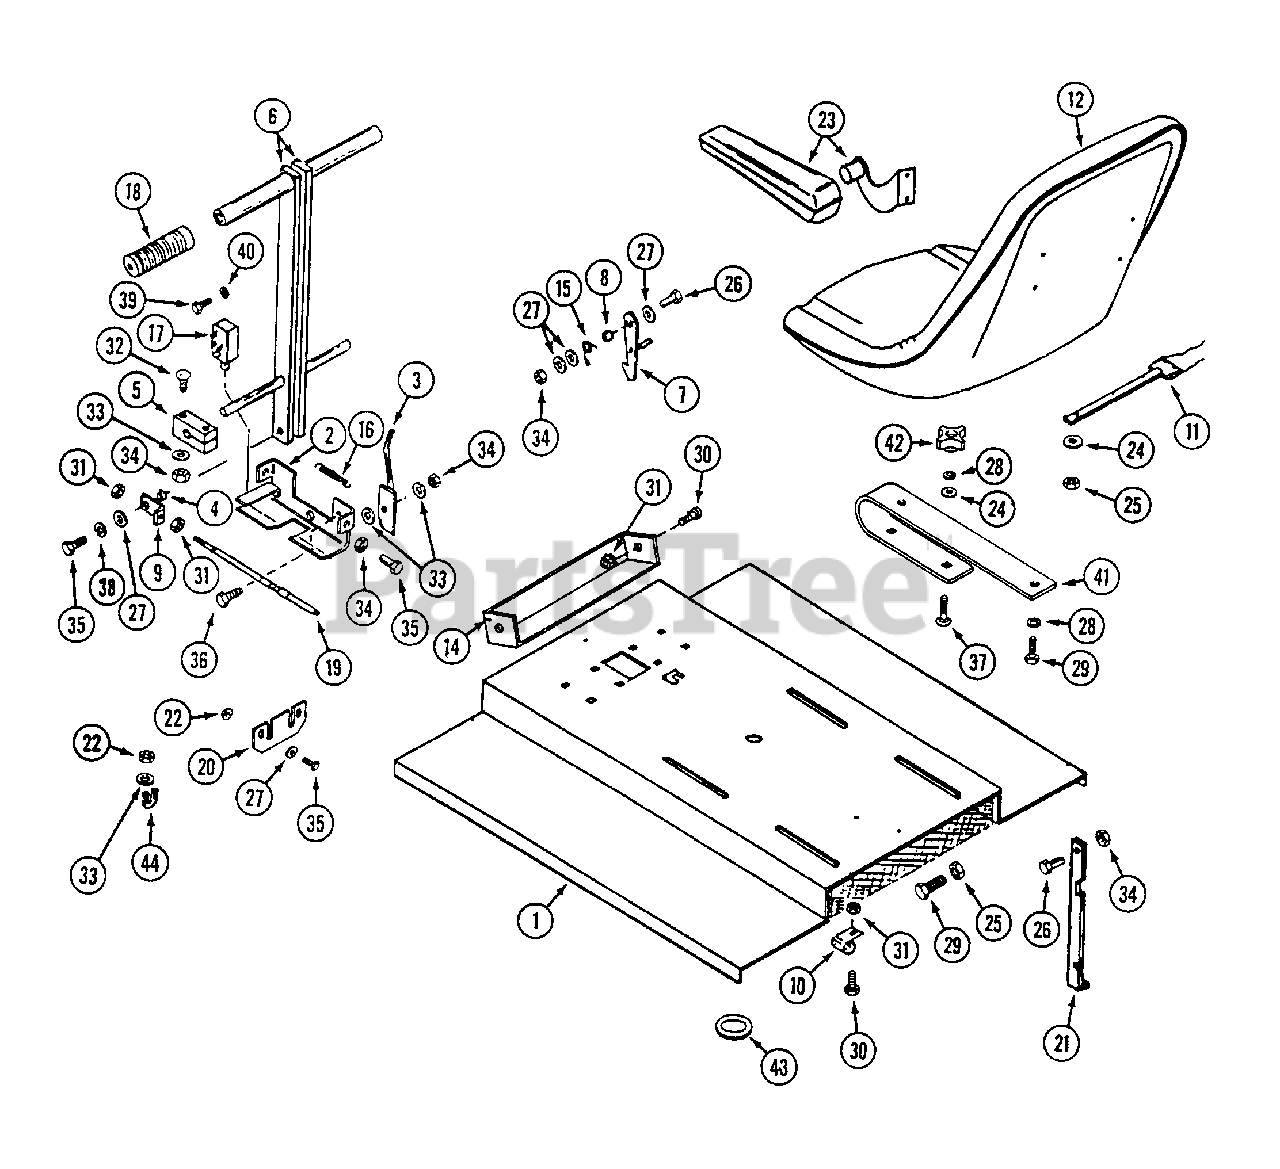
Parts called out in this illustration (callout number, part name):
1	LID - seat
2	BRACKET - lever lock
3	LATCH - lever lock
5	BEARING - block
6	LEVER - steering
7	LATCH - seat lid
8	SPACER - latch
9	BRACKET - steering cable end
10	RETAINER - harness, seat lid
11	SWITCH - seat
14	PLATE - filler
15	SPRING - latch, seat lid
16	SPRING - bracket, lever lock
17	SWITCH - safety
18	GRIP - handle
19	CABLE - steering
20	CLAMP - steering cable
21	PROP - seat lid
22	NOT - 1/4" - 20 flange lock
23	KIT - arm rest
24	WASHER - 5/16"
25	NUT - 5/16"
26	BOLT - 1/4" - 20 x 1-1/4"
27	WASHER - 1/4"
28	LOCKWASHER - 6/16"
29	BOLT - 5/16" - 18 x 1"
30	SCREW - #10 - 32 x 1/2"
32	BOLT - 1/4" - 20 x 1-1/2" carriage
33	WASHER - 1/4"
34	NUT - 1/4" - 20 lock
35	BOLT - 1/4" - 20 x 3/4"
36	BOLT - 1/4" - 20 x 1-1/4"
37	BOLT - carriage 5/16" - 18 x 1-1/4"
38	LOCKWASHER - 1/4"
39	SCREW - #10 - 32 X 3/8"
40	LOCKWASHER - 3/16"
41	SPRING - seat
43	GROMMET - 1" x 1-3/4"
44	CLAMP - steering, cable
